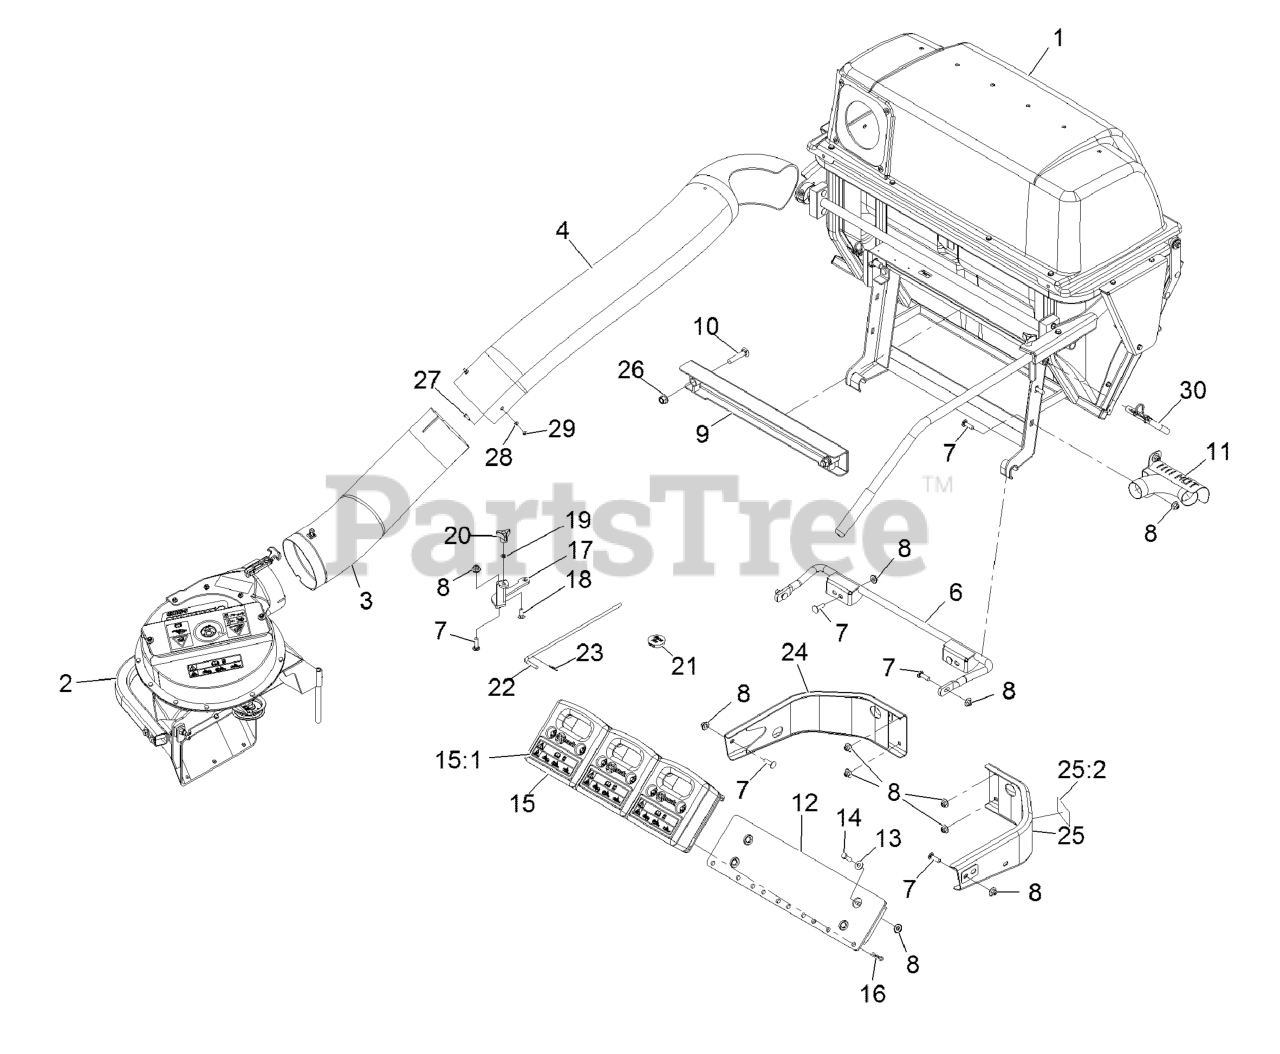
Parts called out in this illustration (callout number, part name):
1	ASM,Hopper Sm Qds
2	ASM, BLOWER SMALL - SVC O
3	LOWER TUBE ASM
4	TUBE-UPPER
6	MOUNT-BAGGER, LOWER
7	Bolt-Carriage 3/8-16 X 1 1/4
8	Nut-Nyloc 3/8-16 Flg
9	MOUNT-BAGGER, UPPER
10	SCREW-CARR
11	EXHAUST DIVERTER ASM
12	WLD, MOUNT TOEBOARD WEIGH
13	WASHER-FLAT
14	SCREW-HH
15	ASM,CAST WEIGHT
15:1	DECAL-WARNING WEIGHT
16	PIN-HAIR
17	BRACKET, SMALL UV BELT CO
18	BOLT-CARR
19	RING-RETAINING, BOLT
20	KNOB-3 PRONG
21	PLUG, BLACK NYLON 1.75
22	PIN,CHUTE PIVOT
23	PIN-COTTER
24	BUMPER-RH
25	LH BUMPER ASM
25:2	DECAL-WARNING
26	Nut-Lock 1/2-13
27	SCREW-HWH
28	WASHER-FLAT
29	NUT-LOCK, NI
30	PIN-MOUNT, BAGGER
